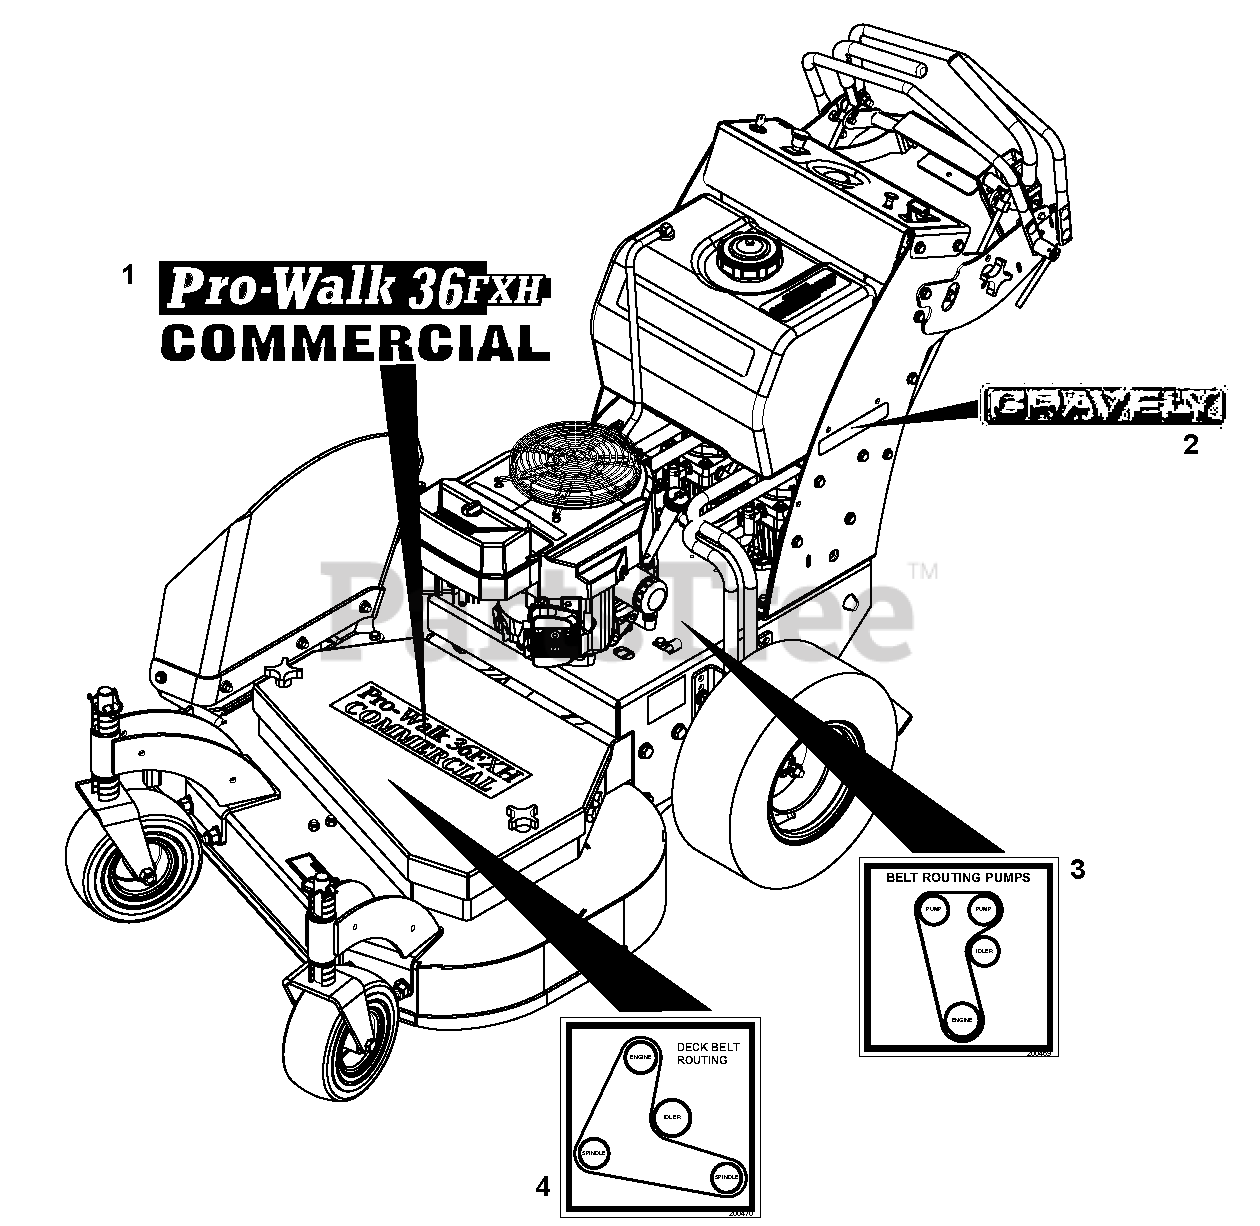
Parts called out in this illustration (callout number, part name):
1	Decal, Gravely Pro-Walk Commercial 36FXH (988140)
2	Decal, Gravely B 6.5"
3	Decal, Pump Belt Routing
4	Decal, 48/52" Deck Belt Routing (988141, 142)
